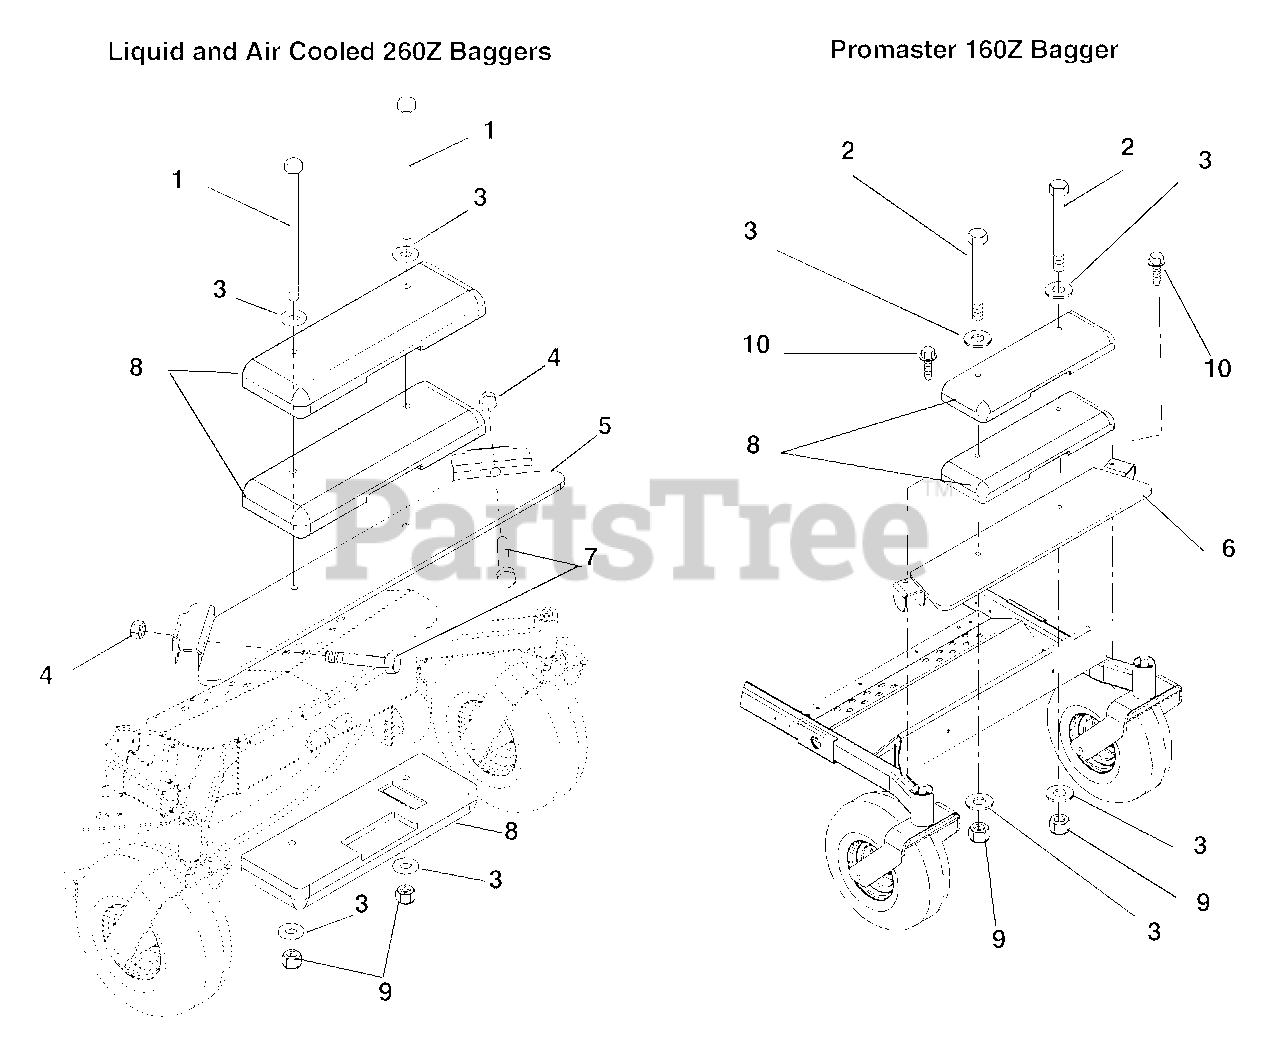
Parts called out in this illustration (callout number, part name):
1	Bolt-Hex .50-13 x 7.50 Grade 5
2	Bolt-Hex .50-13 x 5.50 Grade 5
3	Washer-Flat-Steel .51 x 1.00 x .062
4	Nut-Locking-Nylon .38-16
5	Weldment, Weight Plate (892005)
5	Weldment, Weight Plate (892012)
6	Weldment, Weight Plate (892016)
7	Bolt-Hex .38-16 x 3.00 Grade 5
8	Counterweight
9	Nut-Locking-Center .50-13
10	Tapping Screw, .38-16 x 3/4 (892016)
